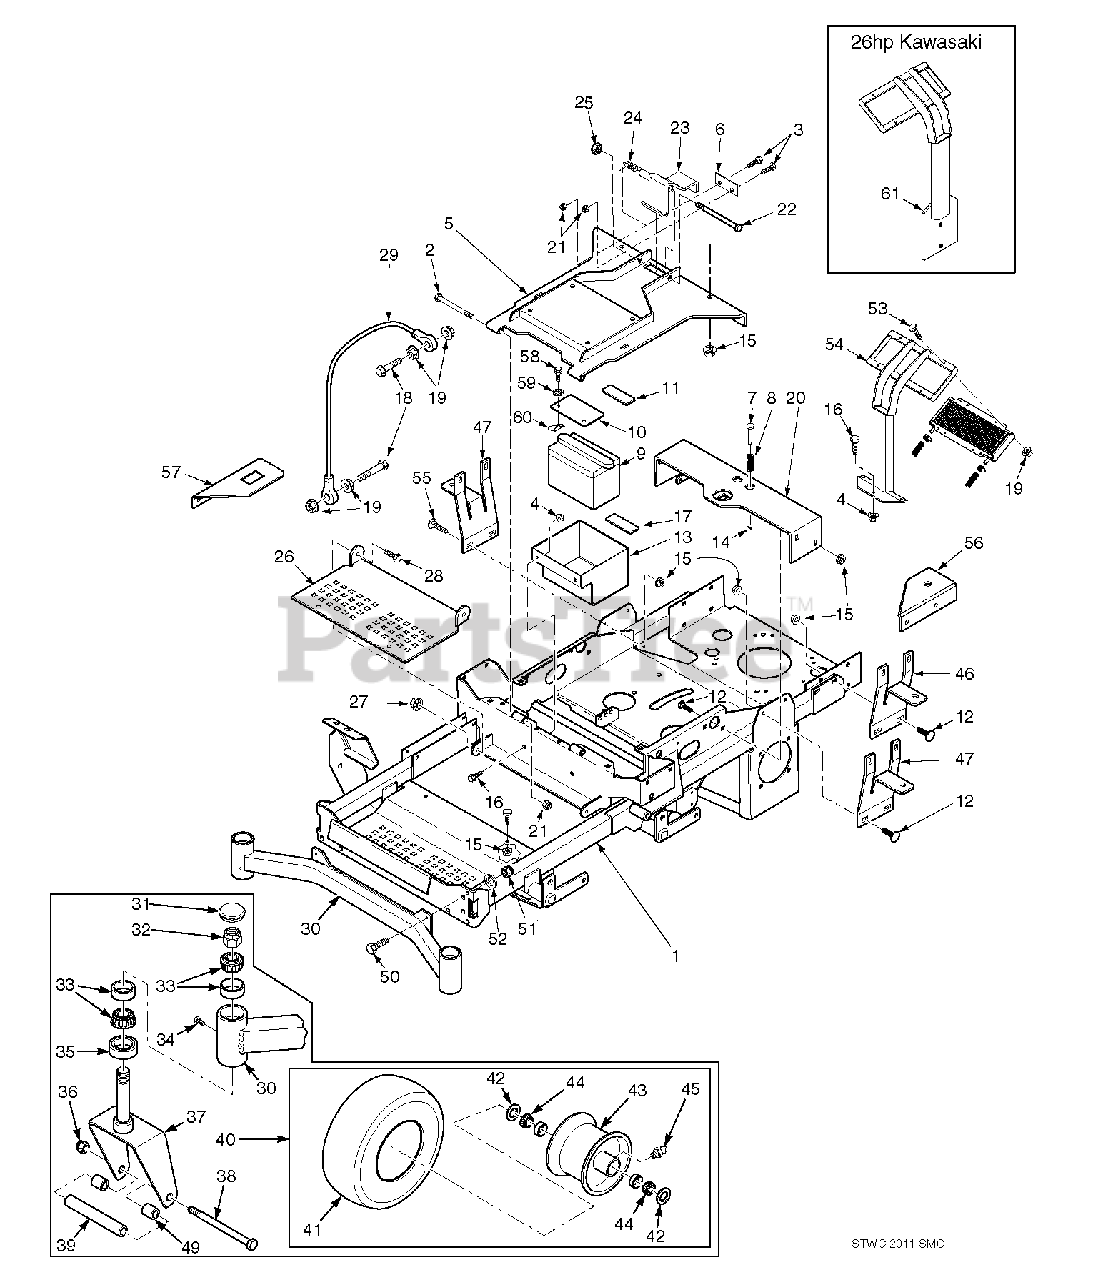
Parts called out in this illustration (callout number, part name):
1	Main Frame Assembly w/Decals
2	Bolt, Hex Hd. 5/16-18 x 3-3/4"
3	Bolt, Hex Hd. 5/16-18 x 1"
4	Nut, Serr. Flng. 3/8-16
5	Plate, Seat Mounting
6	Seat Stop
7	Pin Retainer, Spring
8	Spring
9	Battery
10	Battery Cover
11	Battery Hold Down Pad
12	Bolt, Carr. 5/16-18 x 3/4"
13	Battery Box
14	Roll Pin, Spring 5/32 x 3/4"
15	Nut, Serr. Flng. 5/16-18
16	Bolt, Hex Hd. 3/8-16 x 1"
17	Pad, Rubber
18	Bolt, Hex Hd. 1/4-20 x 1-1/4"
19	Nut, Serr. Flng. 1/4-20
20	Seat Base Support
21	Nut, Elastic Stop 5/16-18
22	Bolt, Hex Hd. 3/8-16 x 6"
23	Seat Latch Weldment
24	Spring, Seat Latch
25	Locknut, 3/8-16 Center Lock
26	Footplate
27	Nut, Elastic Stop 3/8-16
28	Bolt, Hex Hd. 3/8-16 x 1"
29	Cable, Seat Stop
30	Weldment, Caster Support
31	Cap, Grease
32	Nut, Elastic Stop 1.0-14
33	Bearing Set
34	Plug, 1/4-28
35	Seal, 2.0" OD x 1.625" ID
36	Nut, Elastic Stop 1/2-13
37	Yoke, Front Caster Wheel
38	Bolt, Hex Hd. 1/2-13 x 9-1/2"
39	Sleeve
40	Caster Wheel Assembly
41	Tire, 13 x 6.5-6 Smooth
43	Rim
44	Roller Bearing
45	Fitting, Grease
46	Mounting Bracket, Oil Tank
47	Mounting Bracket, Fuel Tank
48	Seat Pan
49	Spacer, Caster Wheel
50	Bolt, Hex Hd. 7/16-14 x 1-1/4"
51	Nut, Elastic Stop 7/16-14
52	Lockwasher, 7/16"
53	Bolt, Hex Hd. 1/4-20 x 5/8"
54	Support Weldment, Oil Cooler
55	Bolt, Carriage 5/16-18 x 1"
56	Bracket, Fuel Valve
57	Bracket, Hour Meter
58	Bolt, Hex Hd. 3/8-16 x 1-1/4"
59	Lockwasher. 3/8" Spring
60	U-Nut, 3/8-16
61	Support Weld, Oil Cooler
